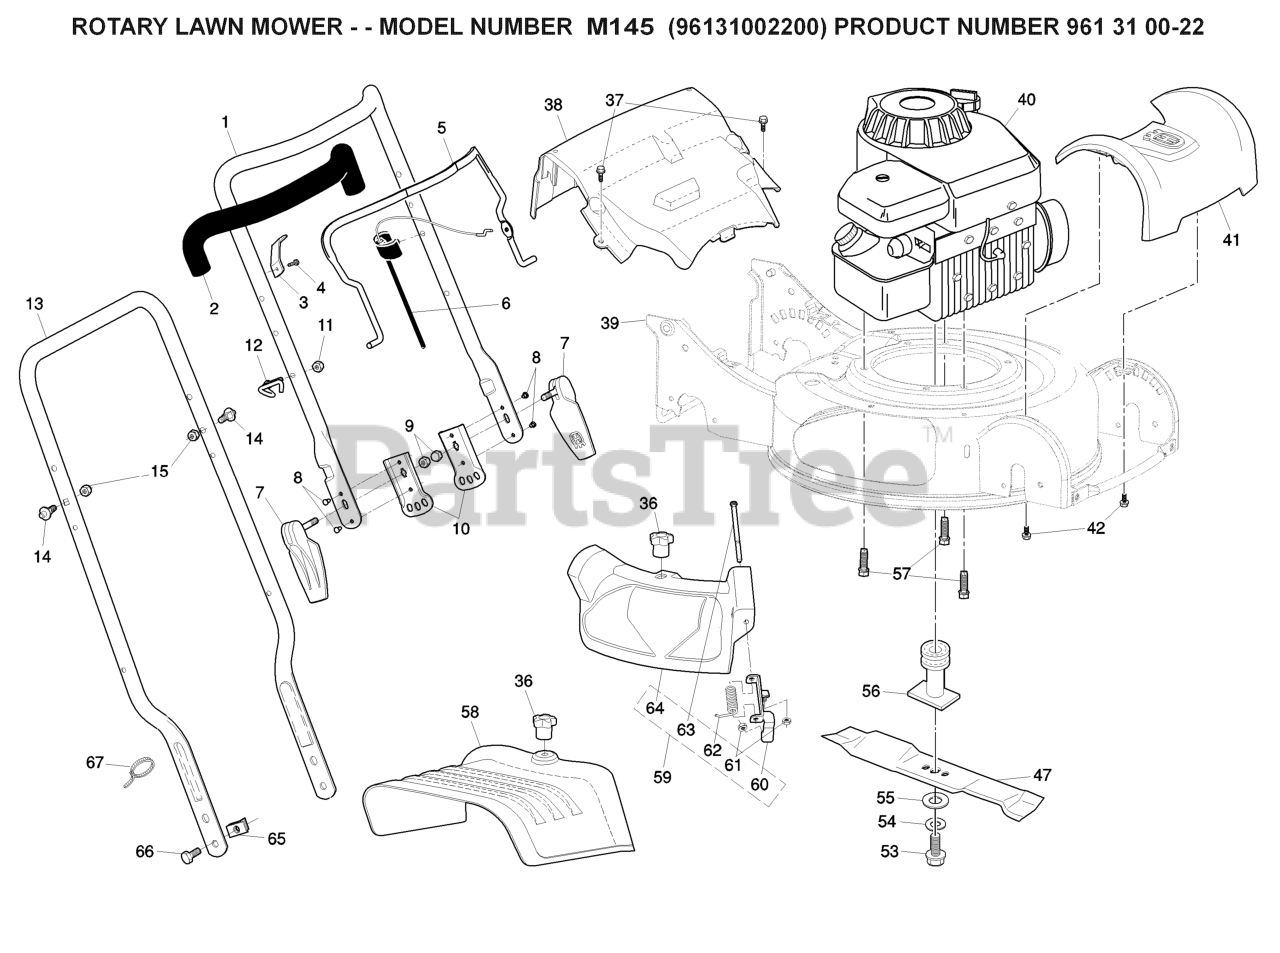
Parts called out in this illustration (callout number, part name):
2	GRIP, FOAM
5	BAIL CONTROL
6	CONTROL.ZONE.ASM
7	ASM.QUICK.RELEASE
9	Locknut, Hex 1/4-20
10	BRACKET.ADJ.3POS.GREY
11	NUT
12	RB GUIDE.ROPE.STD.BLK.ZIN WSL
14	STUD.QUICK.ADJUST
15	NUT.LOCK.5/16-18
36	KNOB.MULCH.DOOR
37	SCREW, HEX WASHER HEAD
42	SCREW.HWH.13-16-5.8.BZP
53	BOLT.HD.HEAD.3/8-24X2.50 (2 2)
54	LOCKWASHER
55	WASHER,HARDEN
57	BOLT 3/8-16X1-1/8
61	NUT.HEX.FLANGE.1/4
62	SPRING.MULCH.DOOR
63	ROD.HINGE.1/4"3.82"
64	DOOR.MULCH.GREY
67	TIE GUIDE
